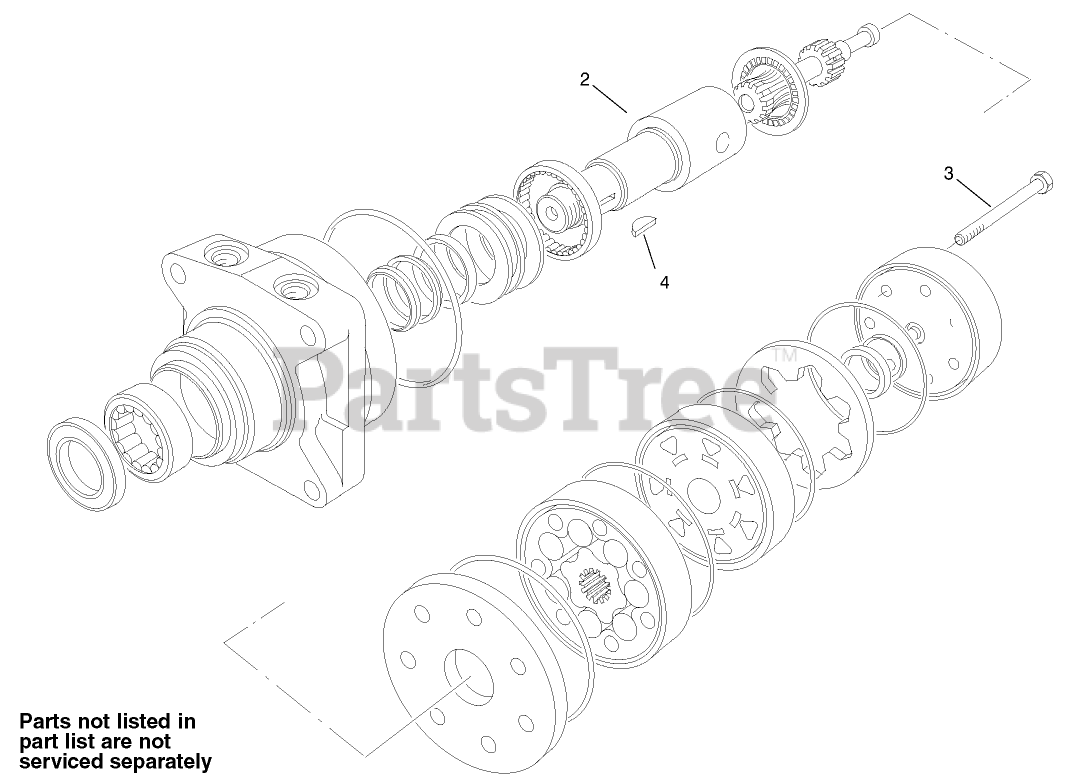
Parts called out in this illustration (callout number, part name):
1	SEAL KIT
1:1	SEAL-DIRT AND WATER
1:2	Washer-Backup
1:3	Seal-Ring
1:4	Washer-Backup
1:5	Seal-Inner
1:6	Seal-Commutator
2	SHAFT-COUPLING
3	SCREW-CAP, HH
4	KEY-WOODRUFF
